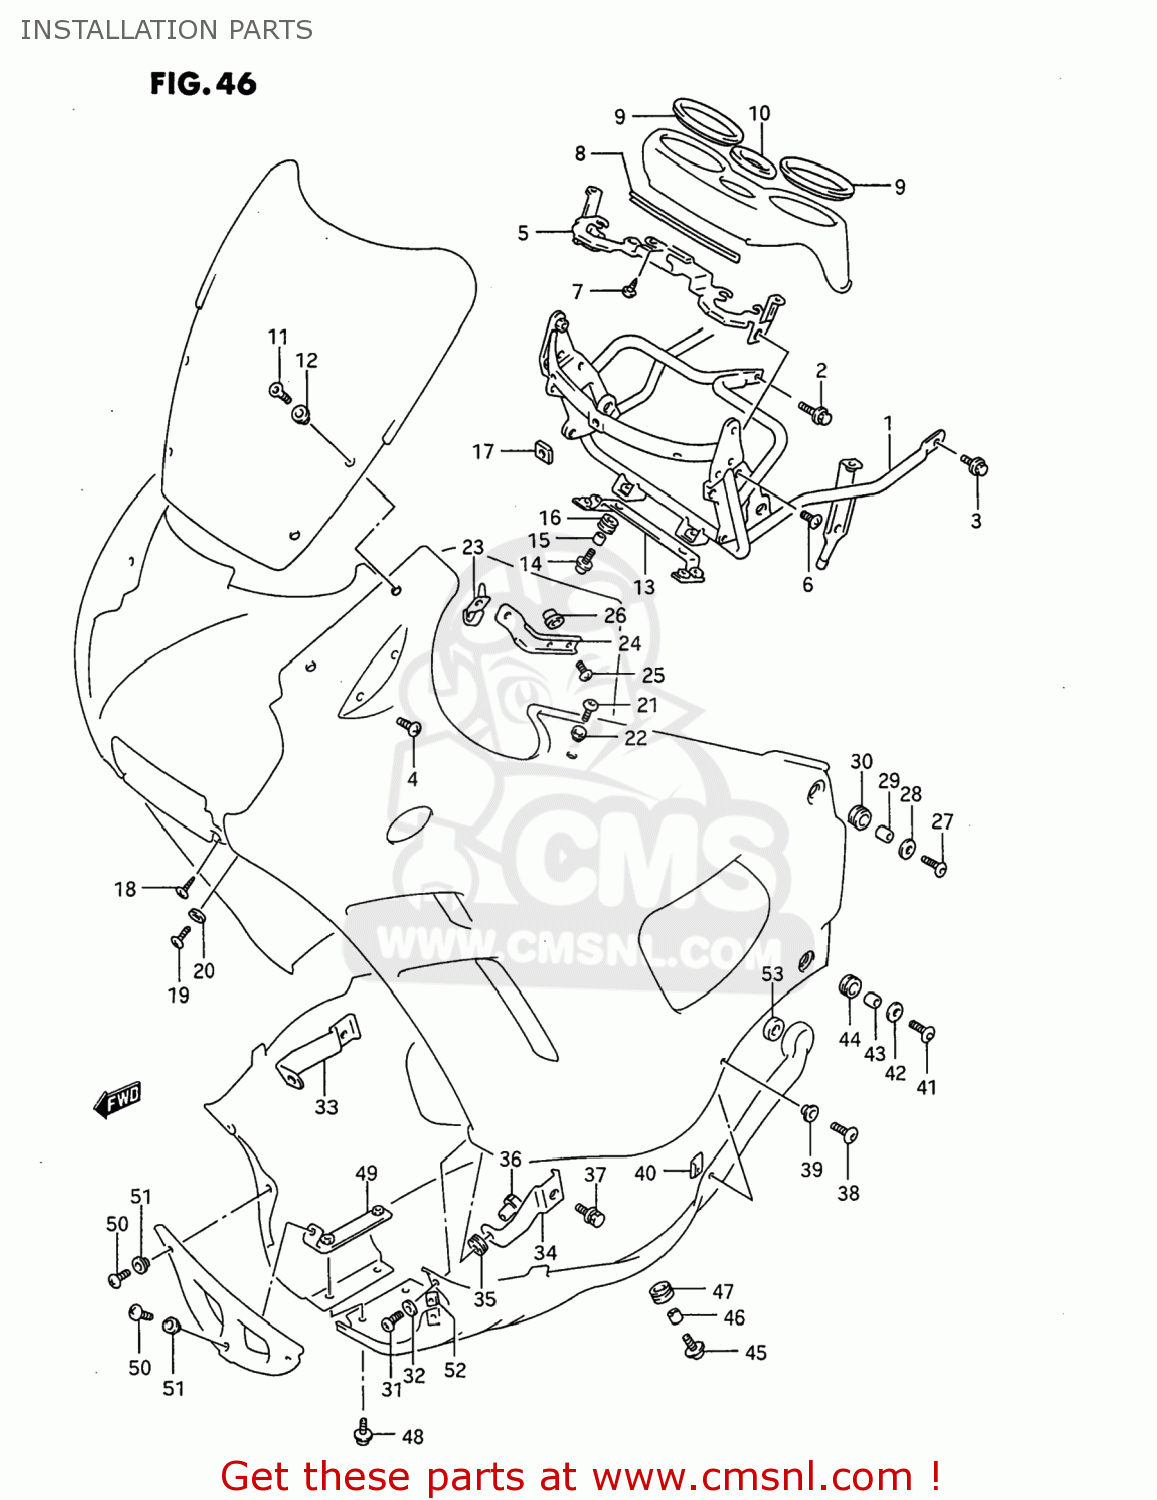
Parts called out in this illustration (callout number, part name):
1	BRACE,COWLING
2	BOLT(8X20)
3	BOLT
4	SCREW 6X12
5	PLATE,METER FITING
6	SCREW 6X12
7	SCREW 5X8
8	MOLDING,METER COVER
9	CUSHION,SPEEDOMETER
10	CUSHION,FUEL METER
11	SCREW
12	WASHER
13	PLATE,COWL CTR PANEL
14	SCREW(6X20)
15	SPACER(6.5X10X9.4)
16	CUSHION
17	CUSHION,SCREEN
18	SCREW 5X12
19	SCREW(6X25)
20	WASHER
21	SCREW(6X16)
22	WASHER(6.3X16X1.5)
23	BRACKET,COWLING UPR,R
24	BRACKET,COWLING UPR,L
25	SCREW
26	NUT,COWLING SIDE BRKT
27	SCREW(6X25)
28	WASHER
29	SPACER(6.5X9X9)
30	CUSHION
31	SCREW(6X30)
32	WASHER
33	BRACKET,COWLING LWR,R
34	BRACKET,COWLING LWR,L
35	CUSHION
36	NUT,COWLING,FR
37	BOLT
38	SCREW(5X14)
39	WASHER(5.2X14X1.5)
40	NUT,HEADLAMP HOUSING,UPPER
41	SCREW(6X25)
42	WASHER
43	SPACER(6.1X8X14.5)
44	CUSHION
45	SCREW(6X20)
46	SPACER(6.5X9X9)
47	CUSHION
48	SCREW
49	BRACKET,FR UNDER COWL
50	SCREW
51	WASHER(5.2X14X1.5)
52	NUT,HEADLAMP HOUSING,UPPER
53	CUSHION,UNDER COWLING RR
